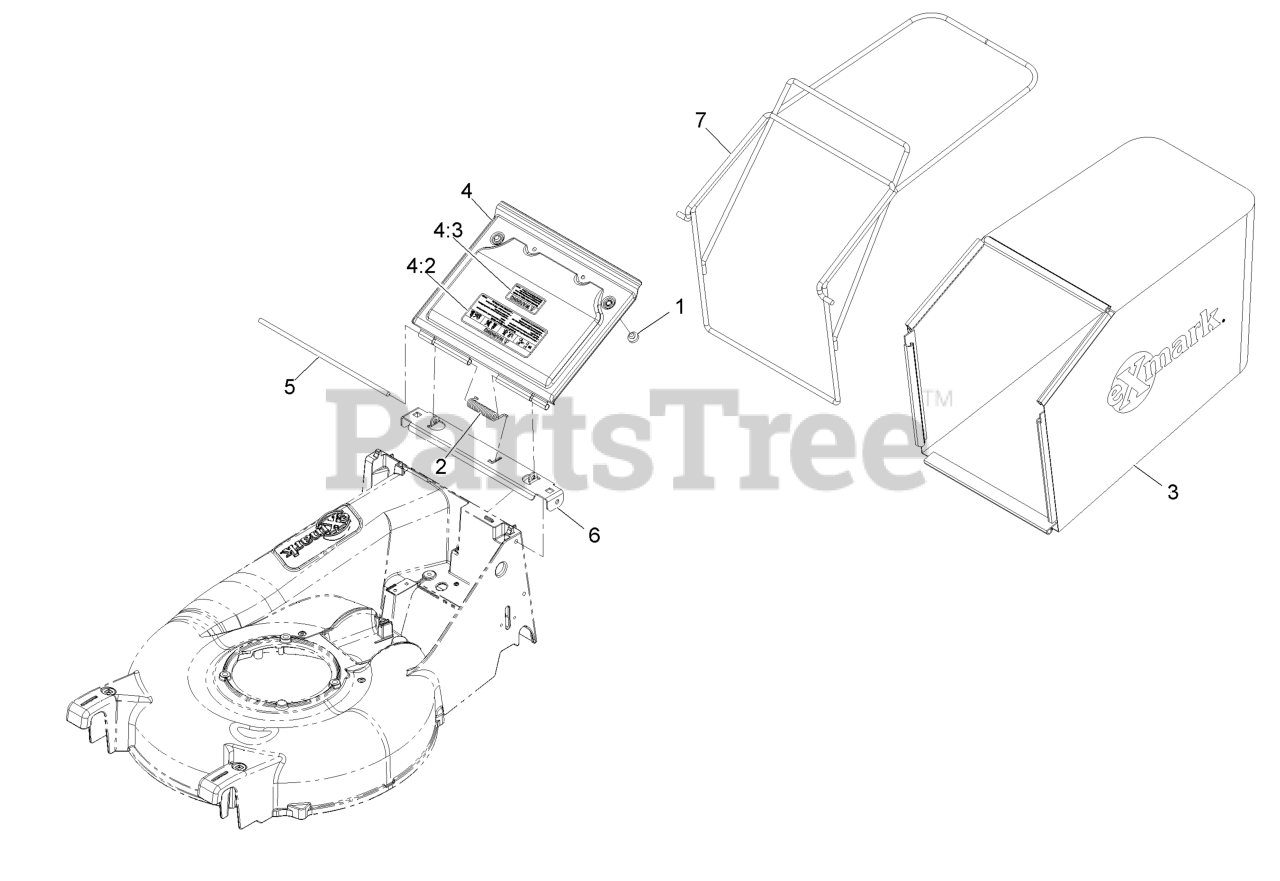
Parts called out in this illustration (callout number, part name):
2	SPRING-TORSION,COVER
3	BAG,GRASS P21
4	DOOR W/DECAL
4:2	DECAL-WARNING
4:3	DECAL-WARNING DOOR SM
5	ROD,DOOR PIVOT
6	BRACKET-DOOR P21
7	WLD,BAG FRAME
